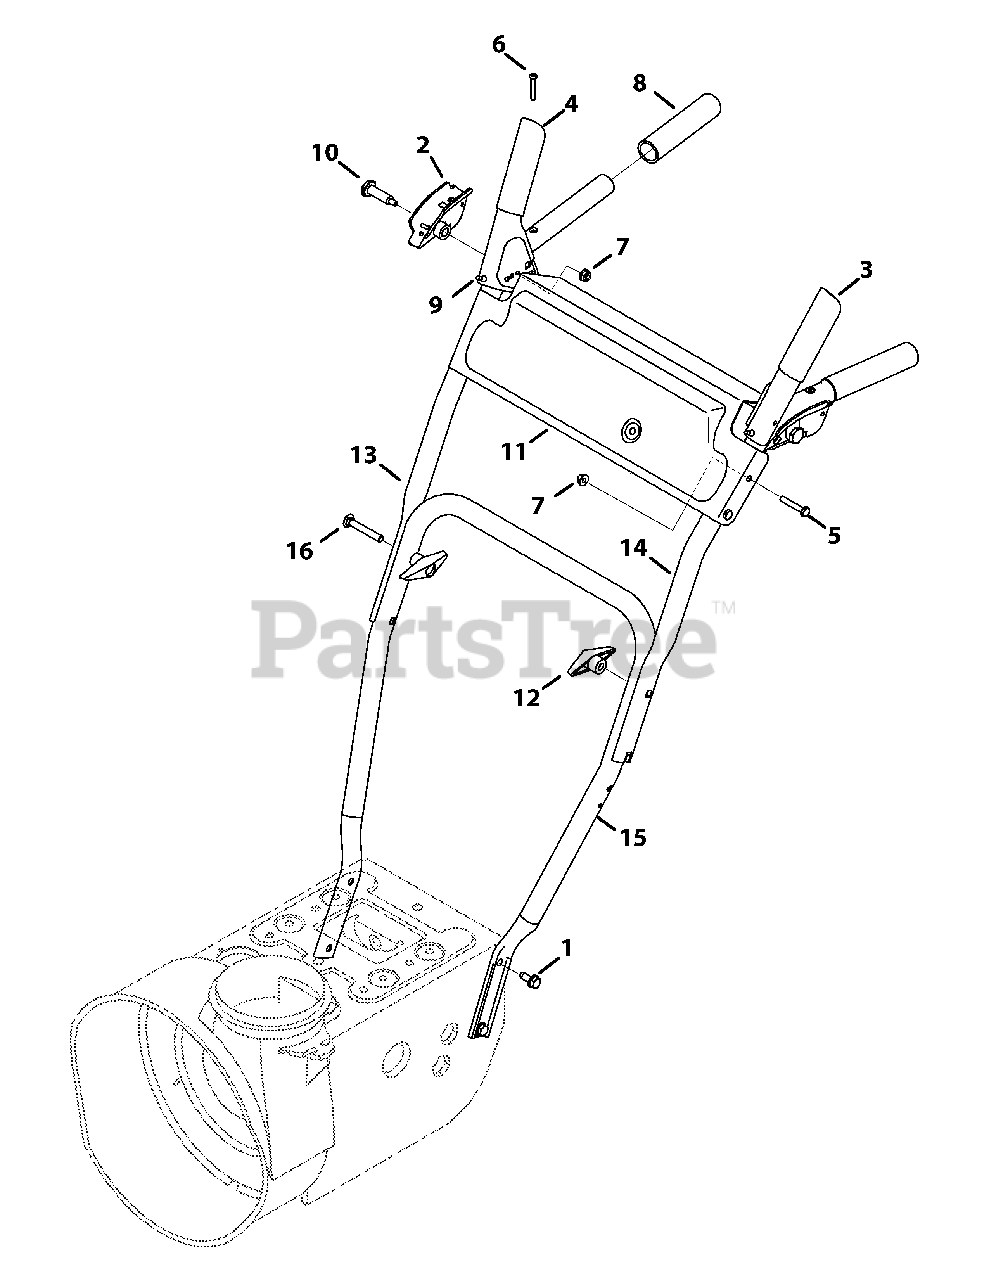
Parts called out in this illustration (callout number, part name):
1	Taptite Screw, 5/16-18 x .750
2	Clutch Lock Handle Assembly, LH
2	Clutch Lock Handle Assembly, RH
3	Engagement Assembly, LH
4	Engagement Assembly, RH
5	Hex Head Screw, 1/4-20 x 1.50
6	Machine Screw, #10-24 x 1.375
7	Flange Lock Nut, 1/4-20
8	Grip, 1.0 ID x 5.0 LG
9	Rubber Bumper, .62 OD x .22 Thick
10	Shoulder Screw, .437 x 1.345 x 1/4-20
11	Handle Panel
12	Wing Knob
13	Upper RH Handle
14	Upper LH Handle
15	Lower Handle
16	Carriage Screw, 5/16-18 x 2.25
